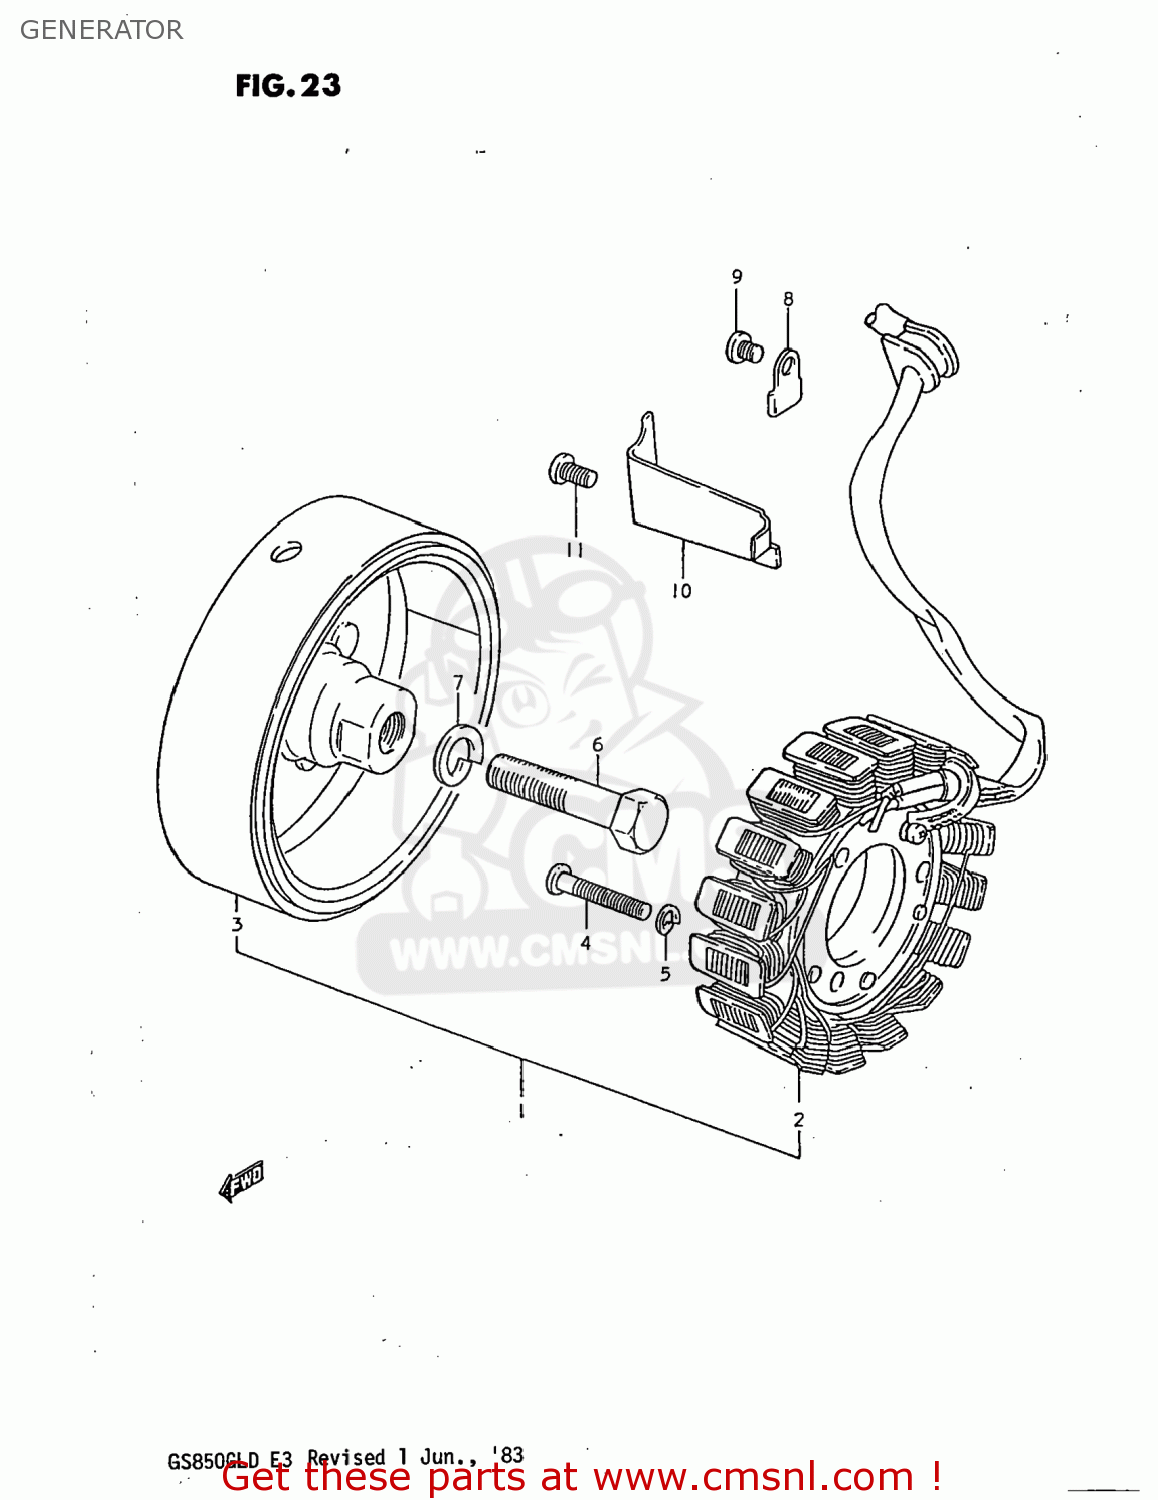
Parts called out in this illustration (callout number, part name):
1	GENERATOR ASSEMBLY
2	STATOR ASSEMBLY
3	ROTOR ASSEMBLY
4	SCREW
5	LOCK WASHER
6	BOLT 12X45
7	WASHER,LOCK 12
8	CLAMP,GENERATOR LEAD WIRE
9	SCREW
10	CLAMP,GENERATOR LEAD WIRE
11	SCREW
